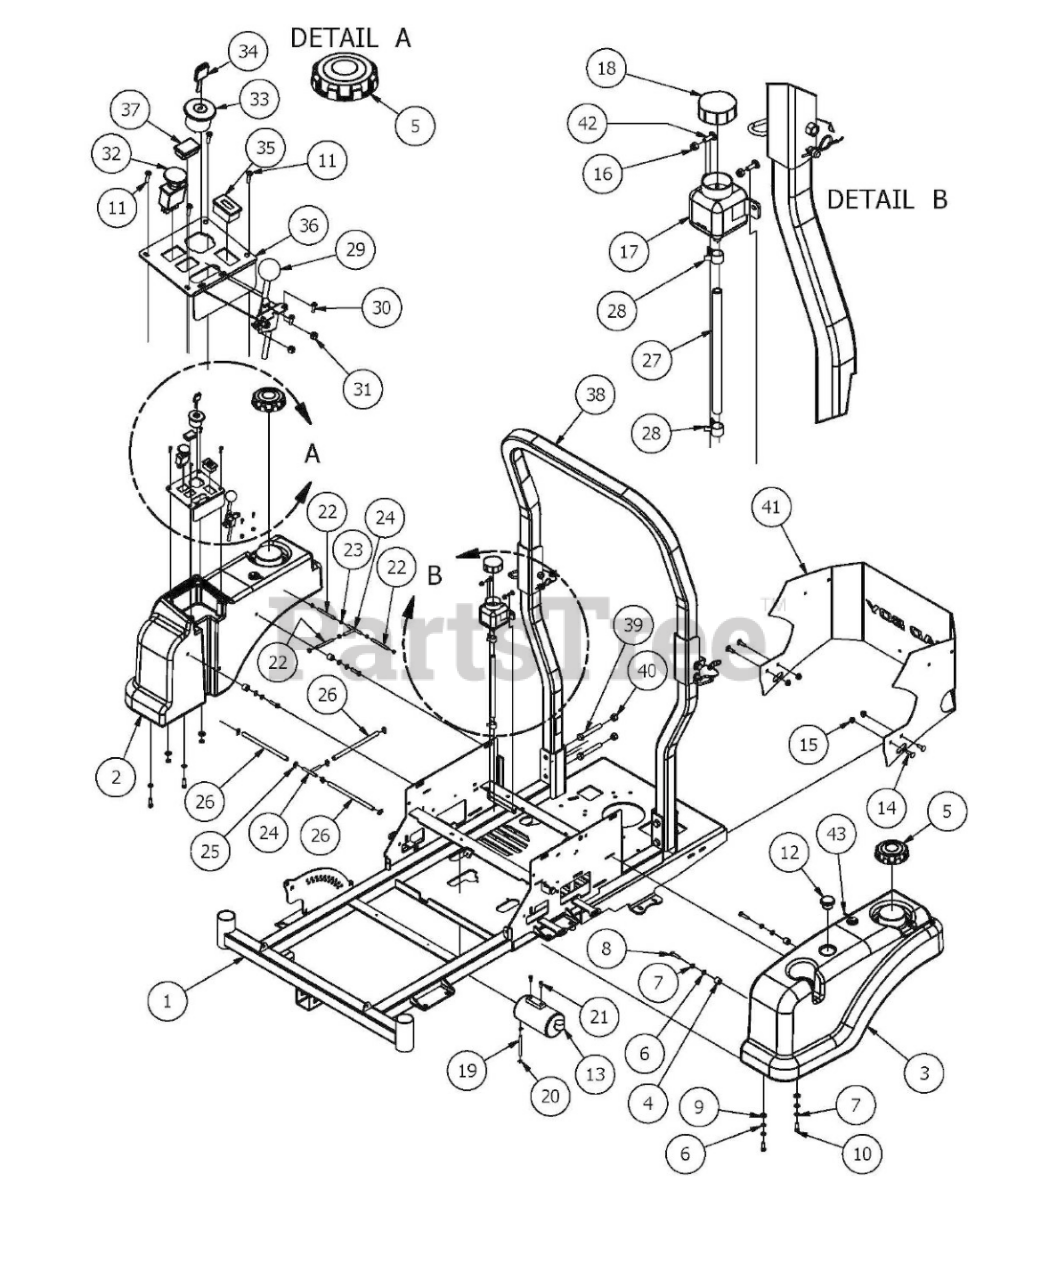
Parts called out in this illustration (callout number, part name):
1	2017 Compact Outlaw Frame
2	Right Fuel Tank/Outlaw/2012/EPA
3	Left Fuel Tank/Outlaw/2012/EPA
4	.380x.735x.470 Nylon Spacer
6	1/4" Flat Washer
7	5/16" Lock Washer
8	5/16 x 1 1/4 Hex Bolt
9	.360 ID Plastic Washer
10	5/16" x 1" Bolt
11	10-32 x 3/8" Button Socket Head Bolt
12	Fuel Gauge Tanks W/downtube
13	Carbon Canister
14	5/16" x 1" Carriage Bolt
15	5/16" Nylock Flange Nut
16	1/4 Nylock Nut
17	350ml Expansion Tank
18	Hydraulic Tank Cap
19	3/16 Vinyl Tubing
20	3/16" Vinyl Hose Clamp
21	M6-1.0 X 16MM Hex Bolt
22	1/4" Vinyl Tubing
23	1/4" Hose Clamp
24	fuel line T
25	1/4 Fuel Hose Clamp
26	1/4" Fuel Line Hose
27	3/8" Clear Hose
28	3/8" Hose Clamp
29	Throttle Lever Assembly
30	10-24 X 5/8 BS Button Head Bolt
31	10-24 Nylon Insert Locknut
32	PTO Switch
33	Ignition Switch
34	Ignition Key
35	Tachometer
36	Control Panel
38	2016 2X2 ROPS
39	1/2-13 x 3 1/2 GR 5 Hex Bolt
40	1/2" Center Lock Nut
41	2017 ZT Rear Plate
42	1/4" x 3/4" Carriage Bolt
43	Rollover Valve
